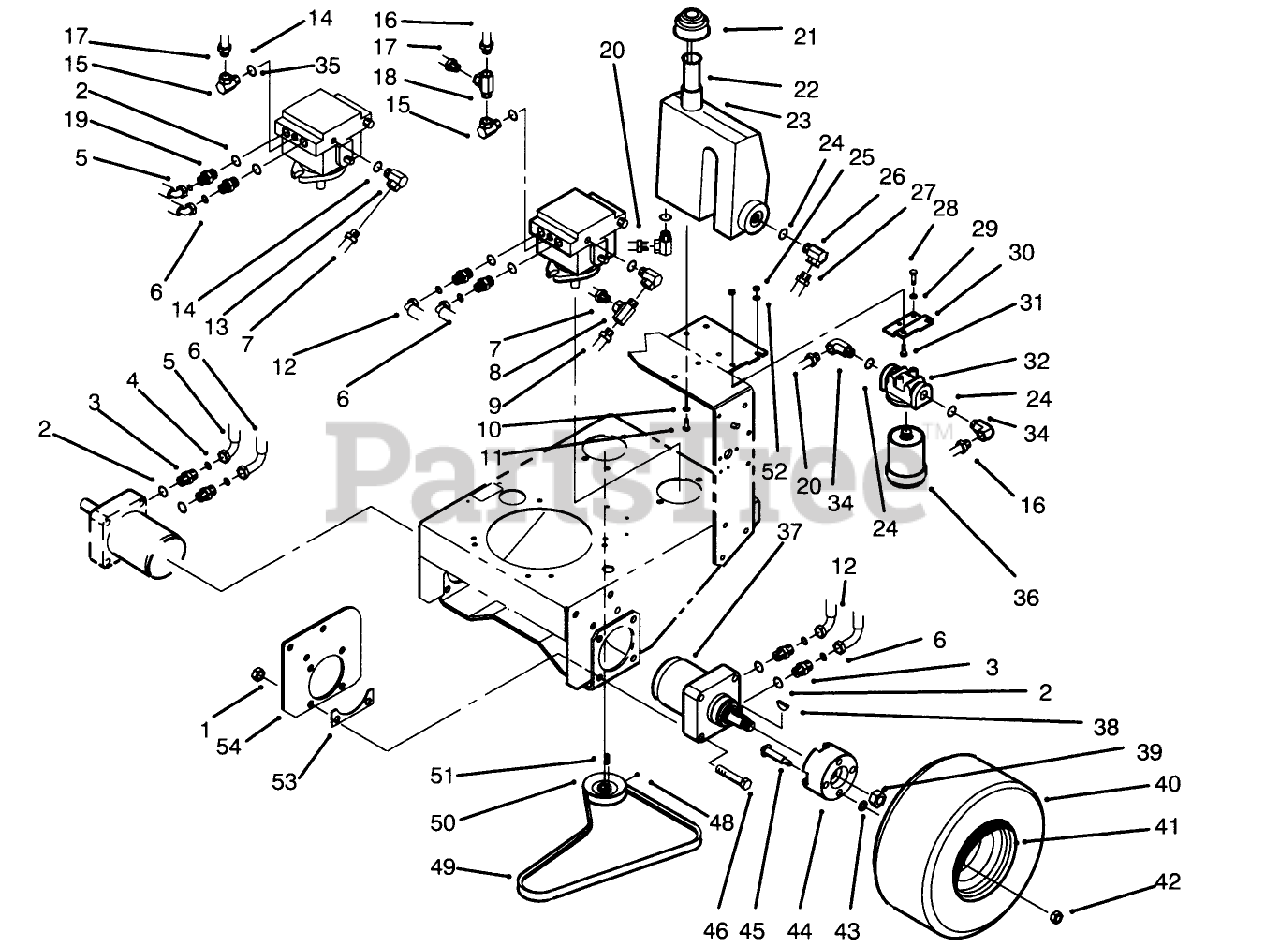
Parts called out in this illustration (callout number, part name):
1	NUT-LOCK, NI
2	O-RING
3	FITTING-STRAIGHT
4	O-RING
5	HYDRAULIC HOSE ASM
6	HYDRAULIC HOSE ASM
7	HYD HOSE ASM
8	FITTING-HYD, TEE
9	HYDRAULIC HOSE ASM
10	WASHER-LOCK
11	WASHER-LOCK
12	HYDRAULIC HOSE ASM
13	FITTING-HYD, 90 DEG
14	O-RING
15	SWIVEL-PIPE, FEMALE
16	HYDRAULIC HOSE ASM
17	HYD HOSE ASM
18	FITTING-HYD, TEE
19	FITTING-STRAIGHT
20	HYD HOSE ASM
21	OIL CAP ASM
22	SCREEN-FILLER
23	Reservoir-Oil
24	O-RING
25	NUT-LOCK, NI
26	FITTING-HYD, 90 DEG
27	HYDRAULIC HOSE ASM
28	SCREW-HH
29	WASHER-LOCK
30	FILTER MOUNTING BRKTR
31	SCREW-HH
32	FILTER HD ASM
34	FITTING-HYD, 90 DEG
35	O-RING
36	CARTRIDGE-FILTER, OIL
37	WHEEL MOTOR ASM
38	KEY-WOODRUFF
39	Nut (Incl. w/Motor)
41	WHEEL
42	NUT-LUG
43	PUSHNUT
44	HUB-WHEEL
45	SCREW-HH
46	SCREW-HH
48	SCREW-SET
49	BELT-V
50	PUMP PULLEY
51	KEY-PUMP
52	WASHER-PLAIN
53	Spacer
54	Plate-Frame
